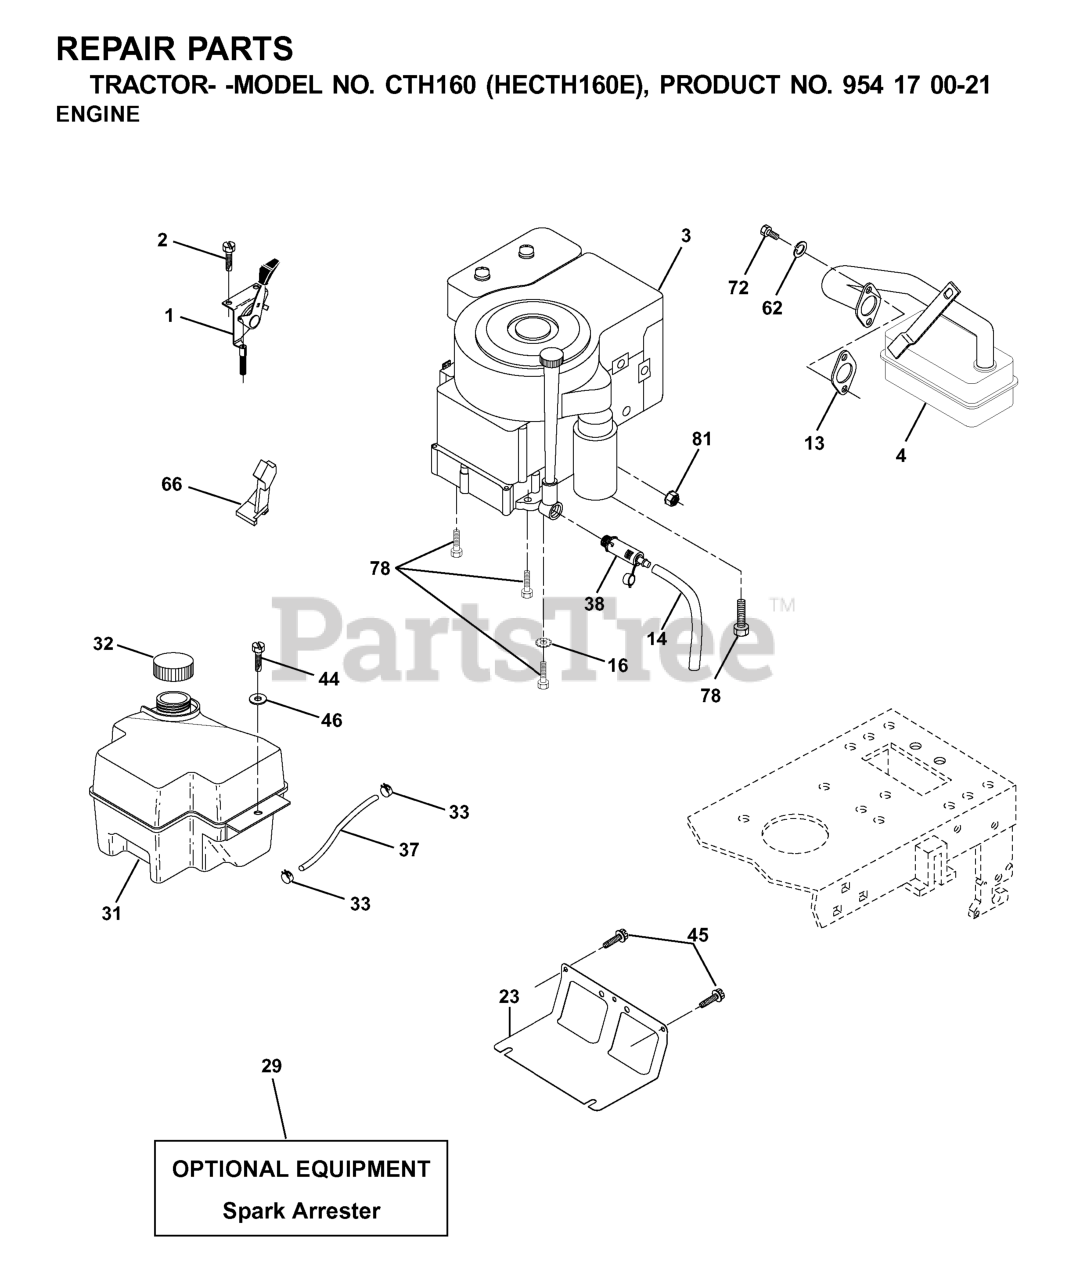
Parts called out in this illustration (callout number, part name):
1	THROTTLE.CONTROL.CABLE.BLACK
2	SCREW LT
4	MUFFLER.LT.BRIGGS.14HP.IC/OHV
13	REPL BY 532 27 22-93
14	TUBE, DRAIN OIL ASM.
16	LOCKWASHER
23	SHIELD.BROWNING.DBR.GUARD
29	KIT.SPARK ARRESTOR 794945 B&S
31	TANK, 2GAL
32	FUEL CAP
33	HOSE CLAMP
37	LINE.FUEL.20
38	PLUG, OIL DRAIN EASY
44	SCREW HEXWSHR 1/4-20X3/4
45	SCREW, 3/8-16X3/4
62	WASHER.LOCK.HVY.HLCL.SPR.5/16
66	STOP THROTTLE
72	SCREW
78	SCREW.3/8-16
81	NUT
